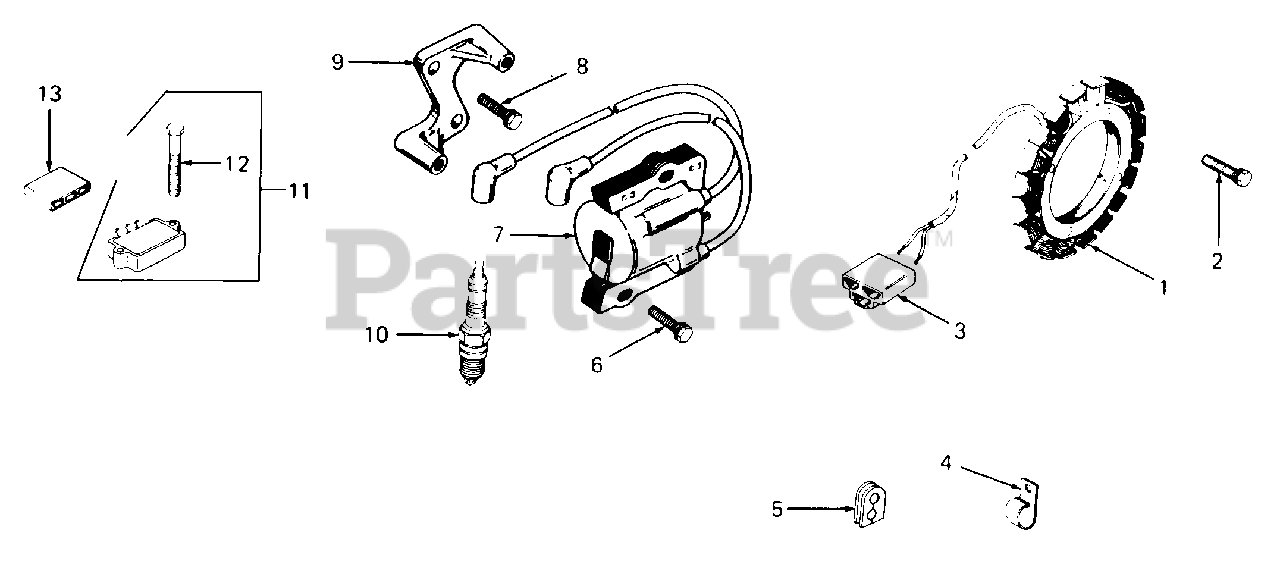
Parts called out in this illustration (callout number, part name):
1	Kit, Stator
2	Screw, Hex Wash Hd, #10-24 X .75 Lg
6	Screw, Hex Wash Hd, 1/4-20 X 1.0 Lg
7	Module, Ignition
8	Screw, Hex Wash Hd, 1/4-20 X .87 Lg
9	Bracket, Module
10	Spark Plug
11	Kit, Rectifier-Regulator
12	Screw, Hex Cap, 1/4-20 X .62 Lg
13	Connector, Rectifier-Regulator
